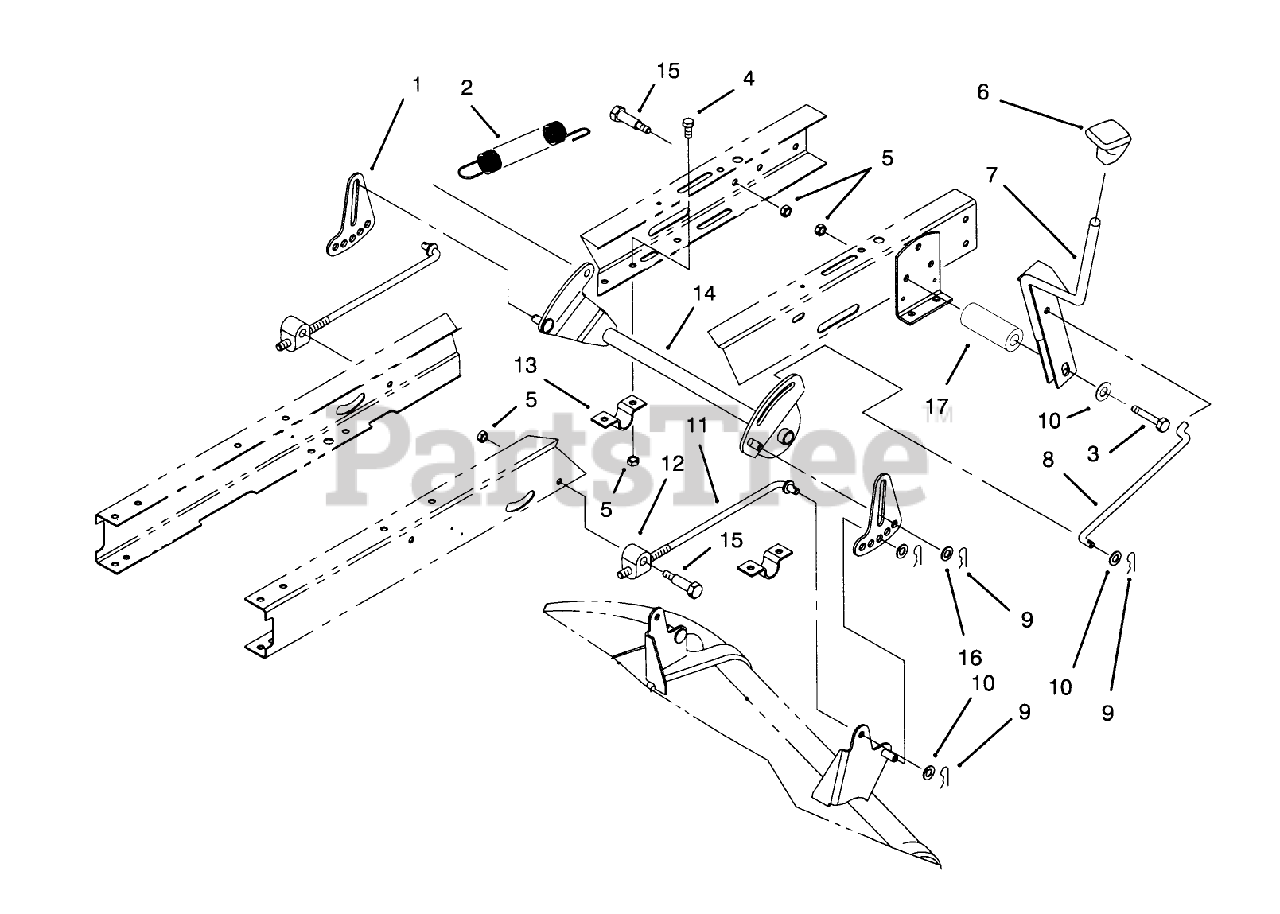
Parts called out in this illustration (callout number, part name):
2	SPRING-EXTENSION
3	SCREW-HH
4	SCREW-HH
5	NUT-LOCK, NI
6	SHIFT KNOB
8	LINK-HOC
10	WASHER-FLAT
11	ROD-HANGER, REAR
12	TRUNNION-HOC
13	CLAMP-PIVOT, HOC
15	SCREW-SHOULDER, HH
16	WASHER-HARDENED
17	SPACER
